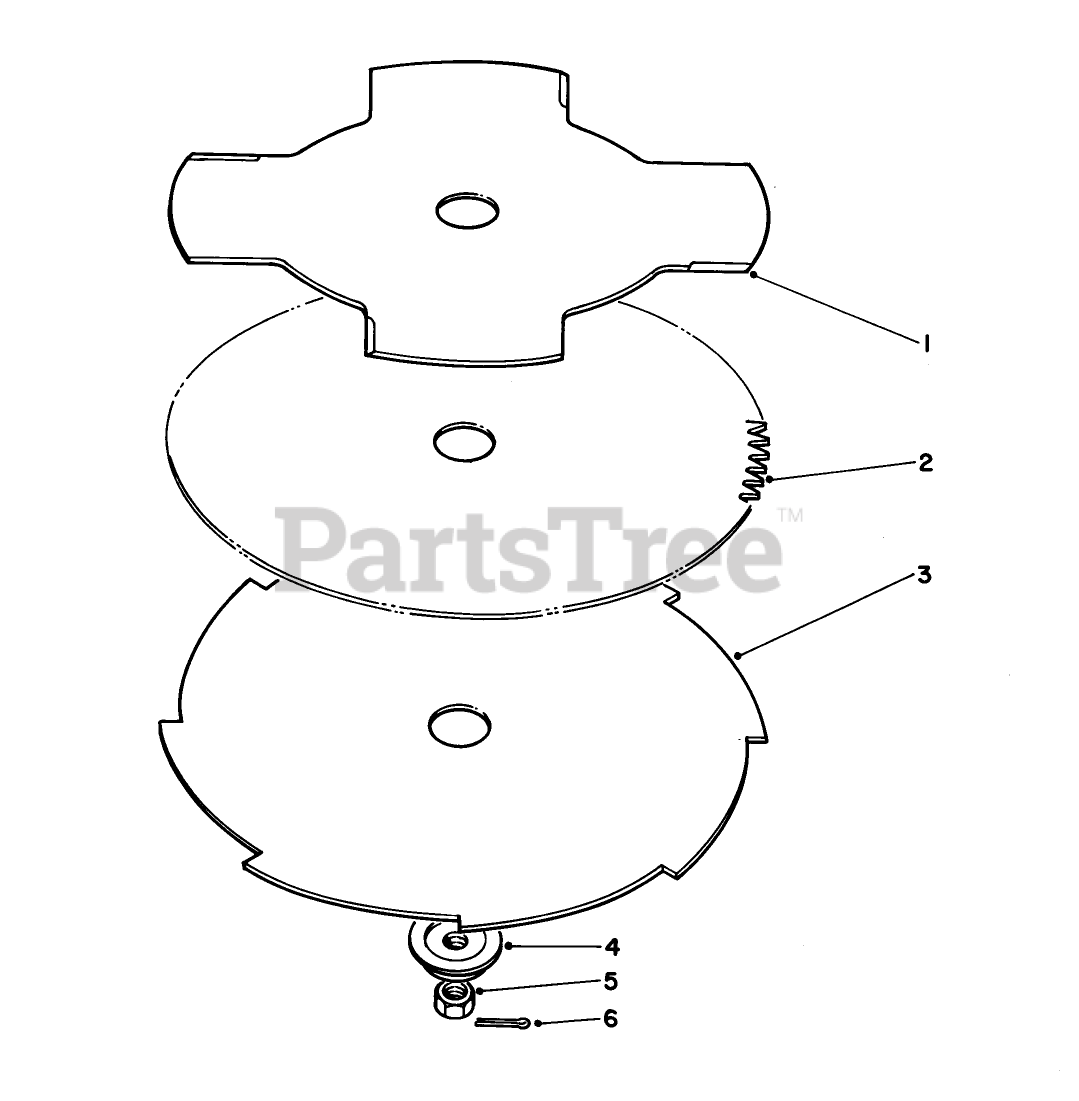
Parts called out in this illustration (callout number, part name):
1	Brush Blade
2	8" Blade (80)
3	8" Blade (8T)
4	Blade Adapter
6	Split Pin
